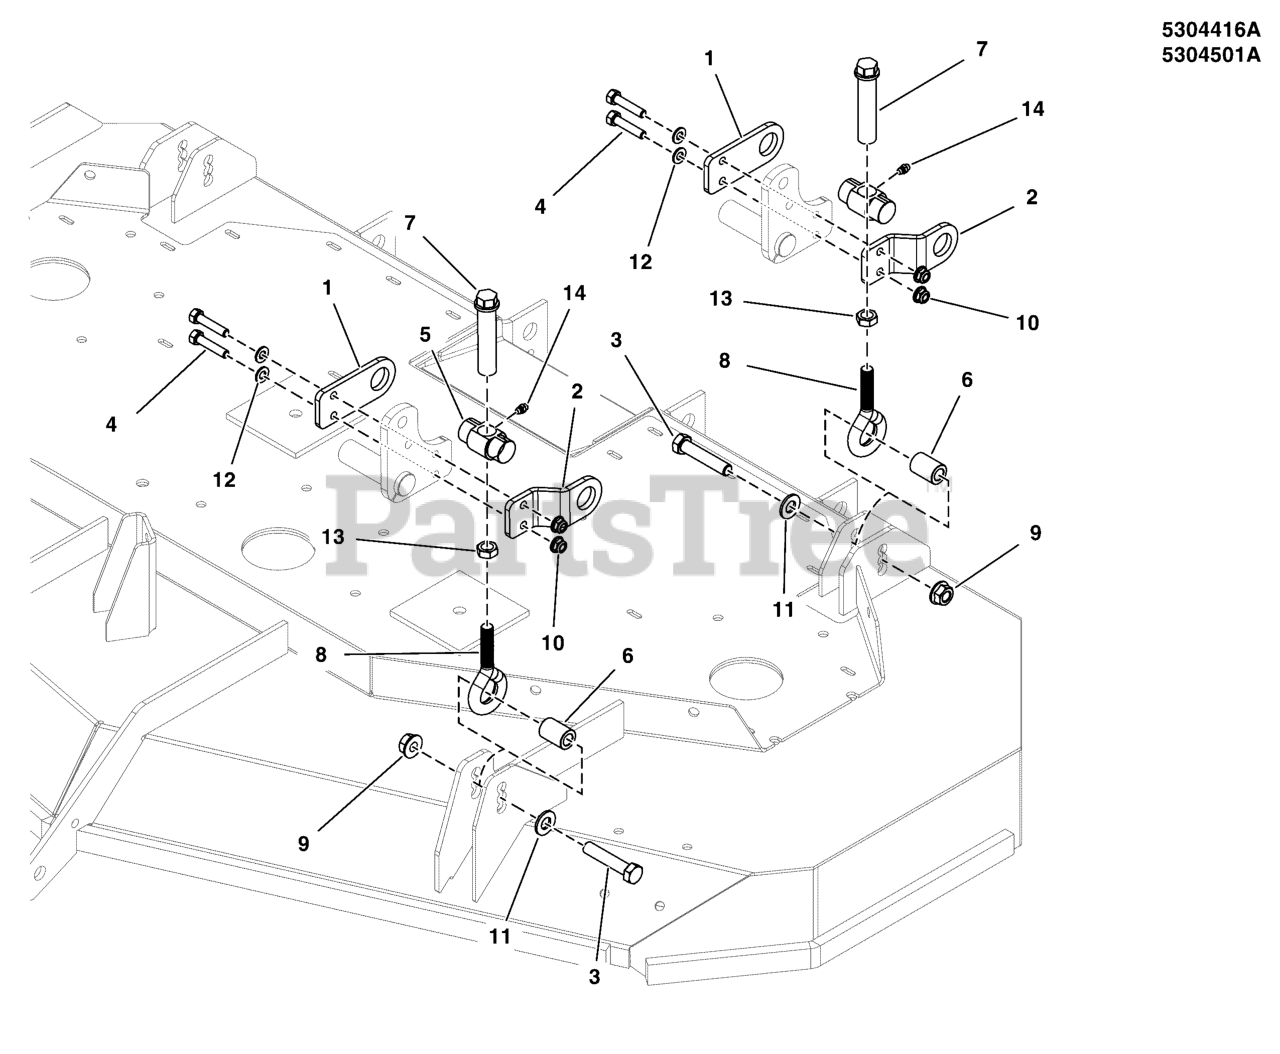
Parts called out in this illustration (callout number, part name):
3	BOLT, 1/2-13 X 2-1/2
4	BOLT, 3/8-16 X 1-1/2"
7	ADJUSTER, HEIGHT
8	EYE BOLT, 1/2-20 X 4.25,1.88THRD,1EYE,CZ
10	NUT, 3/8-16 HEX NYLOCK
11	WASHER, 1/2" SAE
12	WASHER, 3/8 SAE
13	NUT, 1/2-20 HEX JAM
14	GREASE FITTING, 1/4-2
